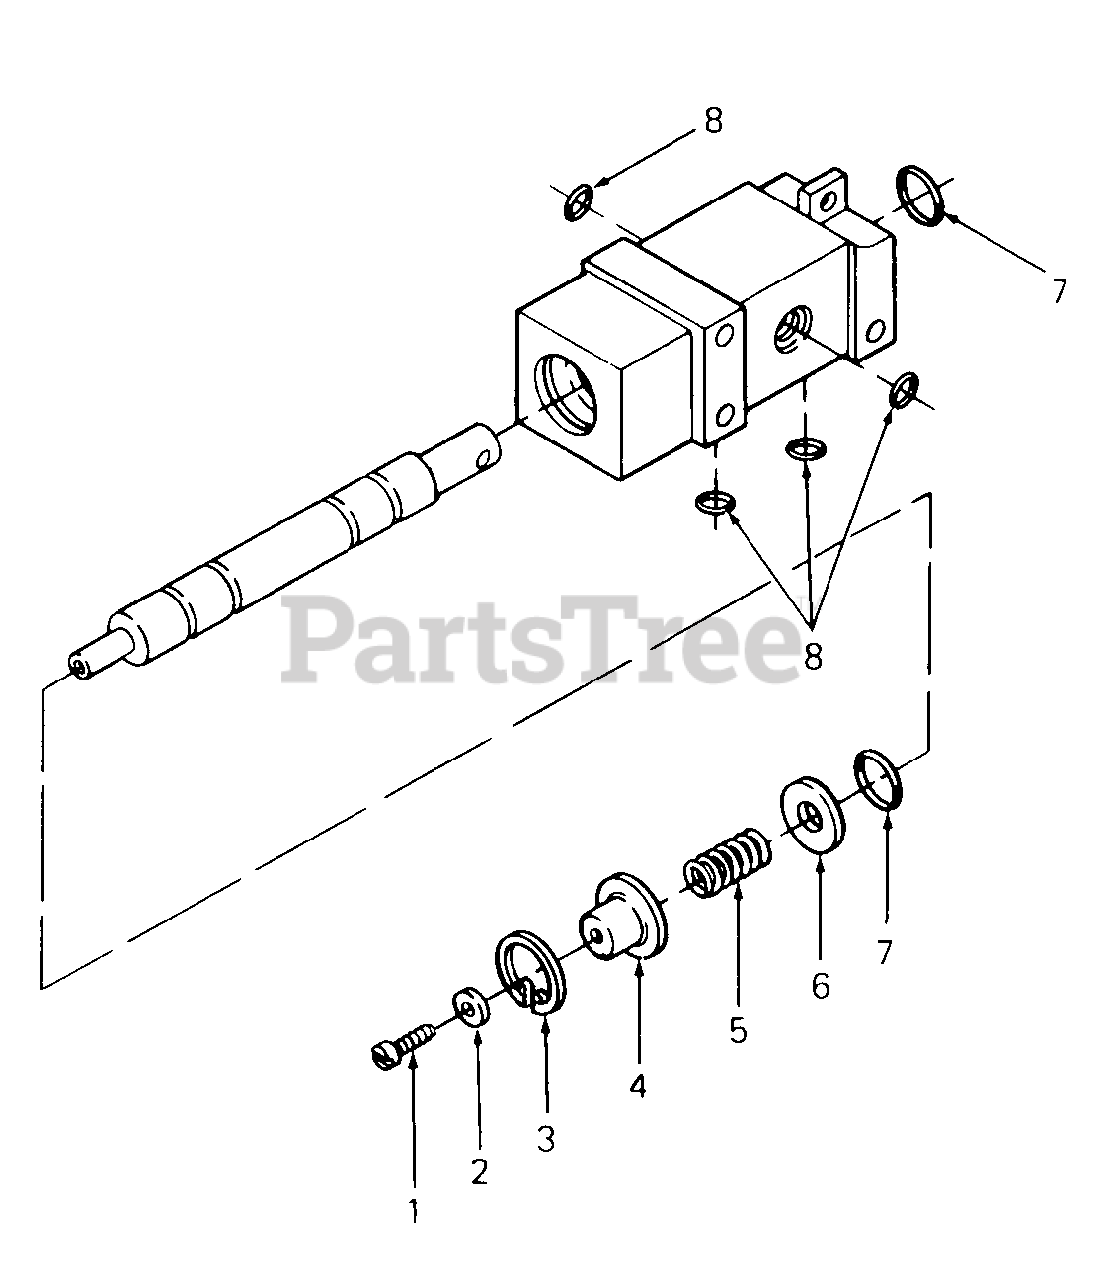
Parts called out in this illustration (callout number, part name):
1	Screw, Truss Mach, #10-24 X .38 Lg
2	Washer, Flat, .218 X .62 X .063 Thk
3	Ring, Int Snap, 1.023 Dia
4	Cup, Centering
5	Spring, Comp, .50 OD X.76 Lg
6	Washer, Flat, .344 X .75 X .105 Thk
7	O-Ring,.424 X.103 Dia
8	O-Ring, .301 X.070 Dia
